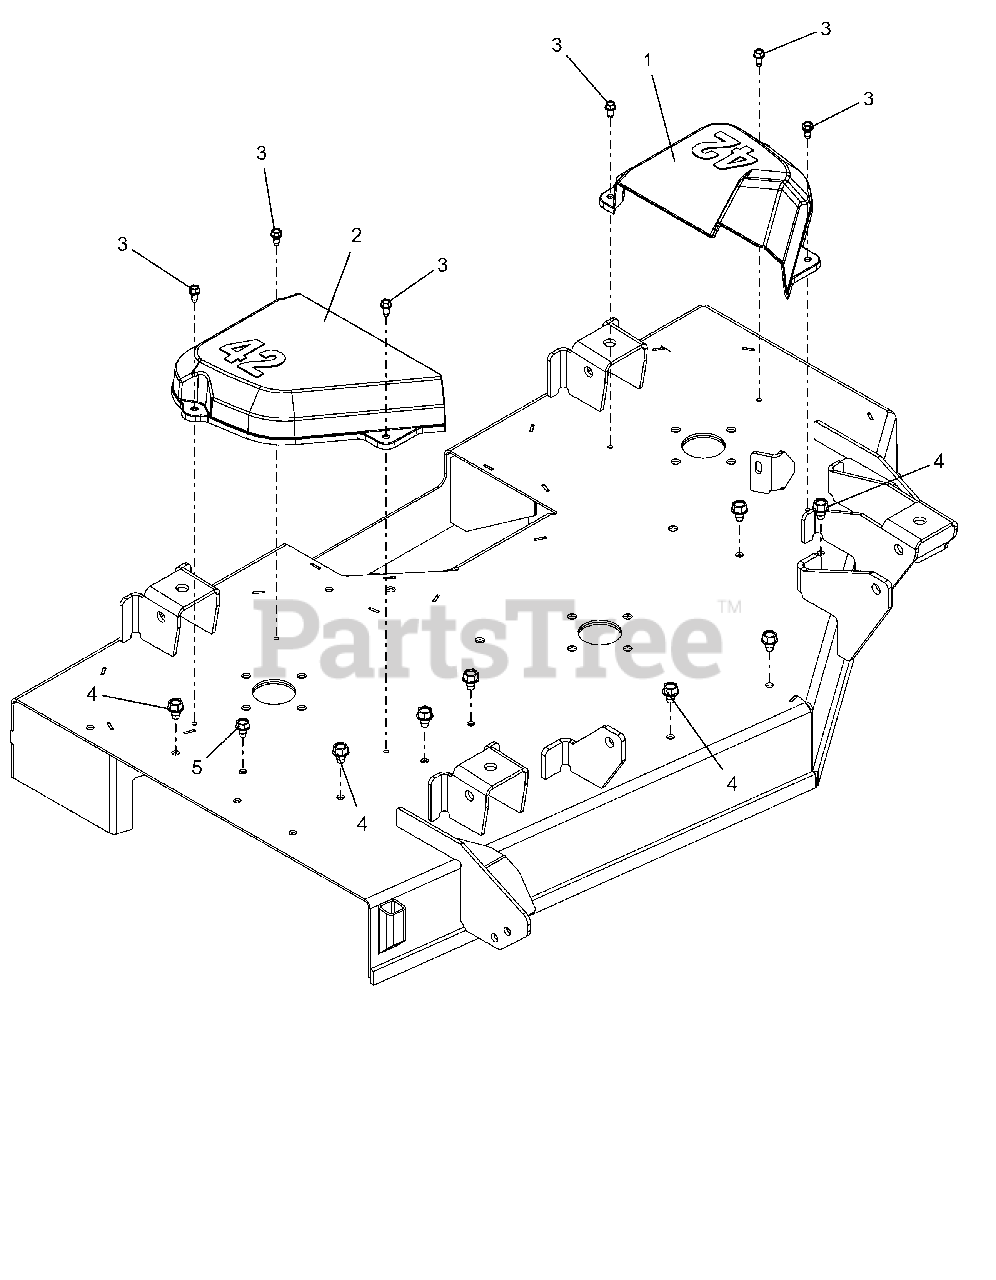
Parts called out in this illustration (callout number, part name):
1	COVER, BELT 42" LH
2	COVER, BELT 42" RH
3	SCR-TAP .25-20X.50 HWH ZCC
4	SCR,TAP .375-16X.50 HWH TR ZCC
5	SCR,TAP .312-18X.50 HWH TR ZCC
